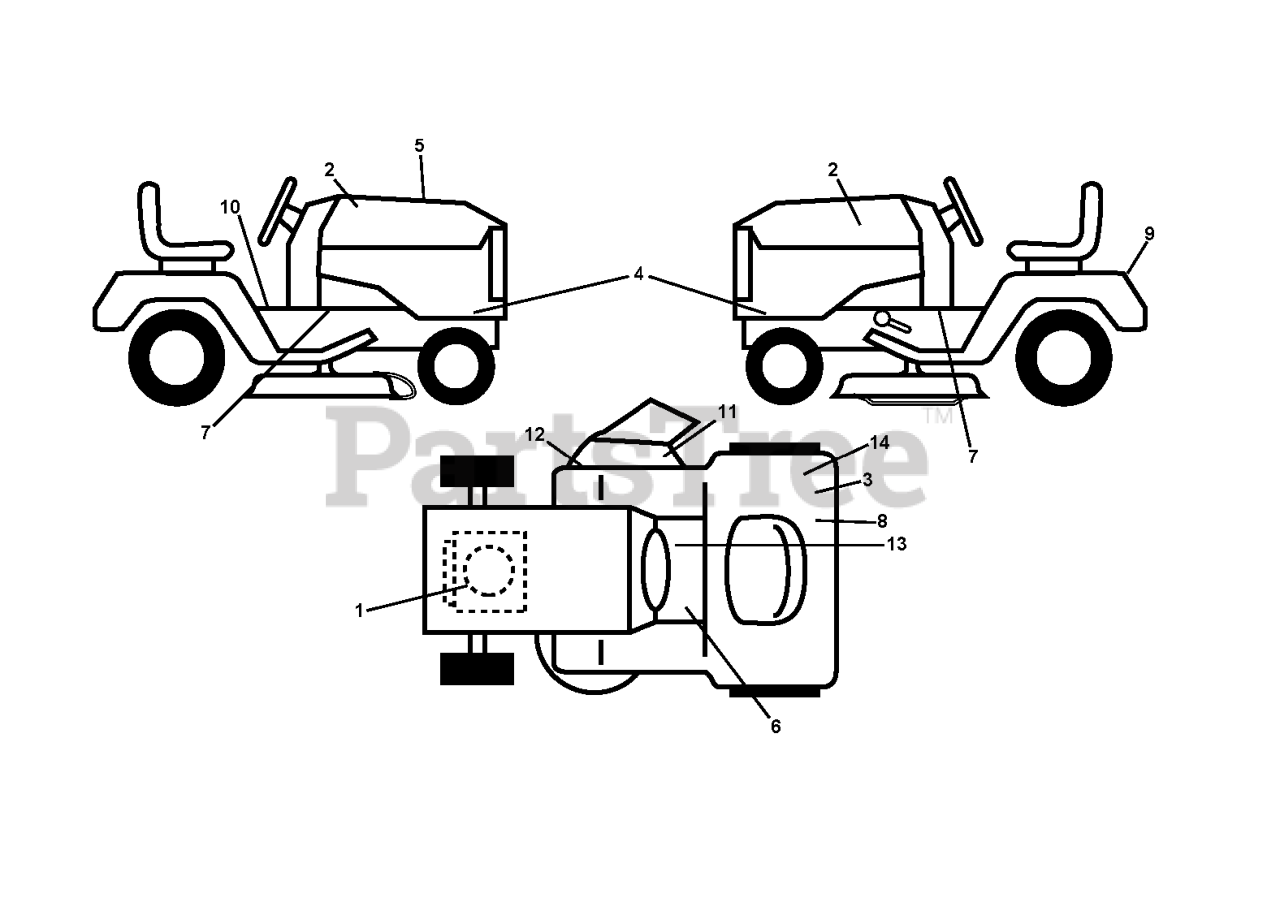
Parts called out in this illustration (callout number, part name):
1	DECAL
2	RP.DECAL.BADGE.170MM.TEXTLOGO
3	DECAL
4	DECAL.SDPNL.LTH19530.
6	DECAL
8	DECAL
9	DECAL BTRY SYMBOLS
10	LABEL
11	DECAL.WARN.DFLECT/CTFINGR.SRD
12	Decal, Mower V-Belt Schematic
13	DECAL PARK BRAKE
14	DECAL 80 DBA
